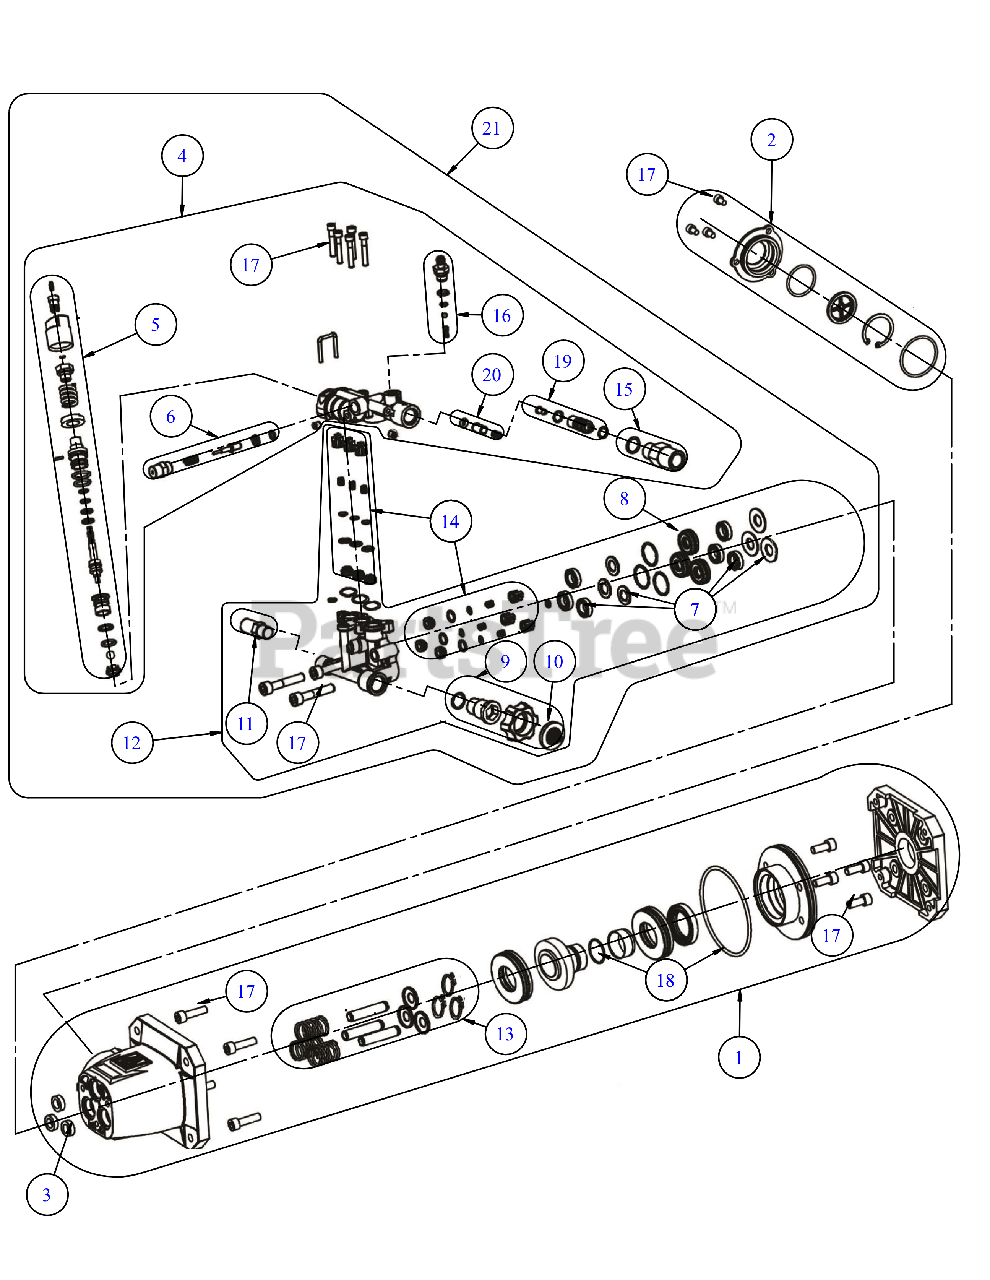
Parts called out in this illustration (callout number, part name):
1	CRANKCASE KIT-PUMP
2	CVR KIT-CRNKCASE SIDE
3	SEAL KIT-OIL
4	MANIFOLD KIT-BYPASS PRESR WASH
5	REPAIR KIT-BYPASS PRESR WASH
6	VLV KIT-PRESSURE BOOST
7	SEAL KIT-WATER PRESR WASH
8	SEAL SPACER KIT
9	INLET KIT-WATER PRESR WASH
10	WATER INLET SCREEN
11	VALVE-THERMAL RELIEF
12	HEAD KIT-PUMP CYL PRESR WASH
13	PISTON KIT-PUMP PRESR WASH
14	VALVE KIT-MANIFOLD
15	CONNECTOR-OUTLET PRESR WASH
16	INJECTOR KIT-SOAP
17	HARDWARE KIT-PUMP PRESR WASH
18	ORING KIT-PUMP PRESR WASH
19	VENTURI KIT
20	VALVE KIT-CHECK PRESR WASH
21	HEAD KIT-PUMP PRESR WASH
